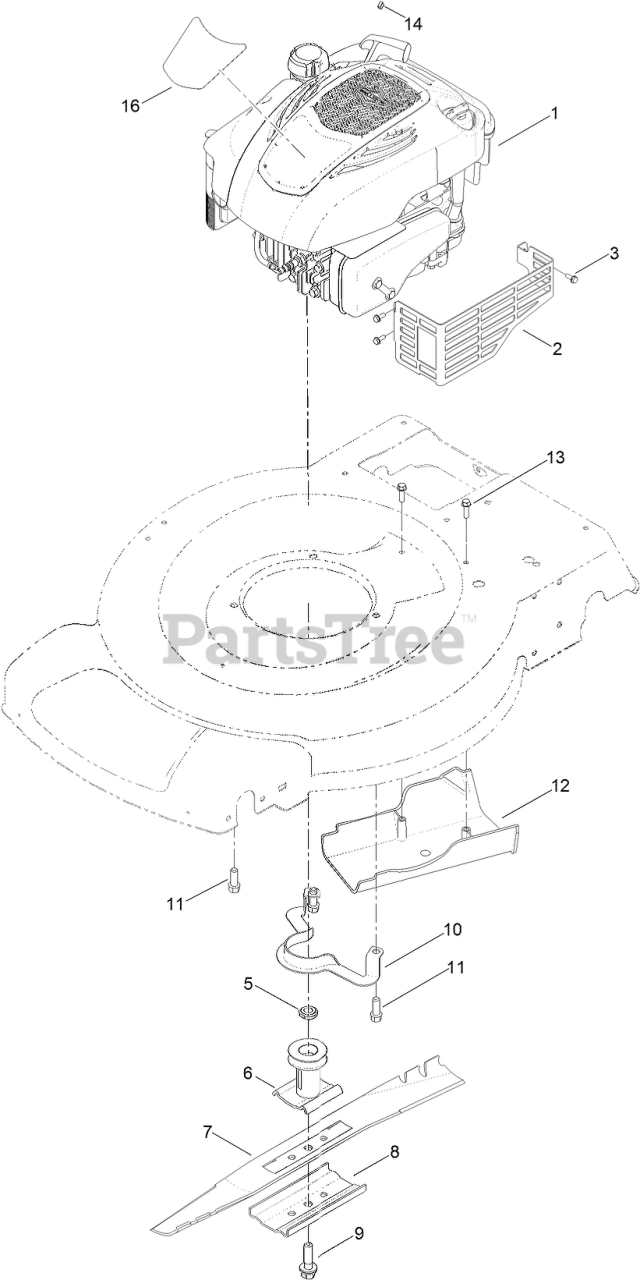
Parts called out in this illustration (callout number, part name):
2	SHIELD-MUFFLER
3	SCREW-TAPTITE
5	Spacer-Driver
6	DRIVER-BLADE
7	BLADE-22 INCH
8	SUPPORT-BLADE
9	BOLT-BLADE
10	Guide-Belt
11	SCREW-TAPTITE
12	COVER-BELT
13	SCREW-HWH
14	STOP-ROPE
16	DECAL-SHROUD
